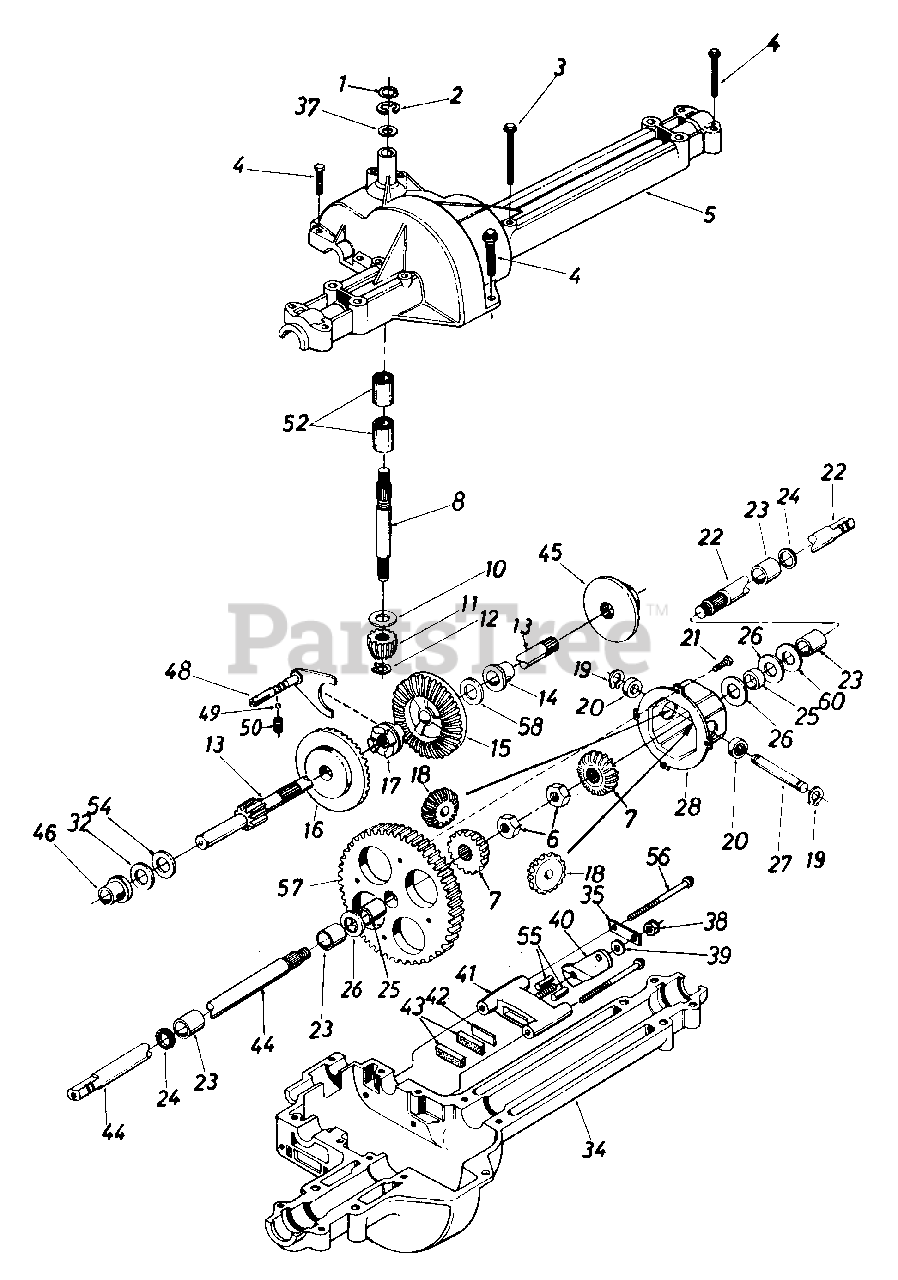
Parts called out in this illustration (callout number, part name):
3	Hex Wash. TT-Tap Scr. 1/4-20 x 1.75" Lg.
4	Hex Tap Scr. 1/4-20 x 1.25" Lg.
5	Upper Housing
6	Hex Jam Nut 1/2-20 Thd.
7	Miter Gear
10	Thrust Washer 5/8" I.D. x 1.25" O.D.
11	Pinion Input 14T
12	Retaining Ring
13	Drive Shaft - R.H. Brake
14	Flange Brg. 5/8" I.D. x 3/4" Lg.
15	Bevel Gear 42T Small I.D.
16	Bevel Gear 42T Large I.D.
17	Clutch Collar
18	Miter Gear 15T (H.D.)
19	Snap Ring
20	Thrust Bearing
21	Pan Head Scr. 1/4-20 x .50" Lg. w/Patch
23	Sleeve Bearing 3/4" I.D. x 1.0" Lg.
24	Oil Seal 3/4" I.D.
26	Fl-Wash. .760" I.D. x 1.5" O.D.
28	Differential Can Ass'y.
32	Washer
34	Lower Housing
35	Anti-Rotation Brkt.
37	Washer
38	Hex Nut 5/16-24 Thd.
39	Fl-Wash .344" I.D. x .875" O.D
40	Actuating Arm
41	Brake Yoke
42	Puck Plate
43	Brake Puck
46	Flange Bearing 5/8" I.D. x 15/16" Lg.
48	Shift Fork Ass'y.
49	Ball Detent .250" Dia.
50	Spring Detent
52	Needle Brg. 5/8" 1.0. x 1/2" Lg.
54	Fl-Wash. 5/8" I.D. x 1" O.D. x .020 Thk.
55	Actuating Pin 5/16" Dia.
56	Hex Wash Hd. Self-Tap Scr. 1/4-20 Thd.
57	Differential Gear 58T
58	Fl-Wash. 5/8" I.D. x 1" O.D. x .020 Thk.
60	Washer
